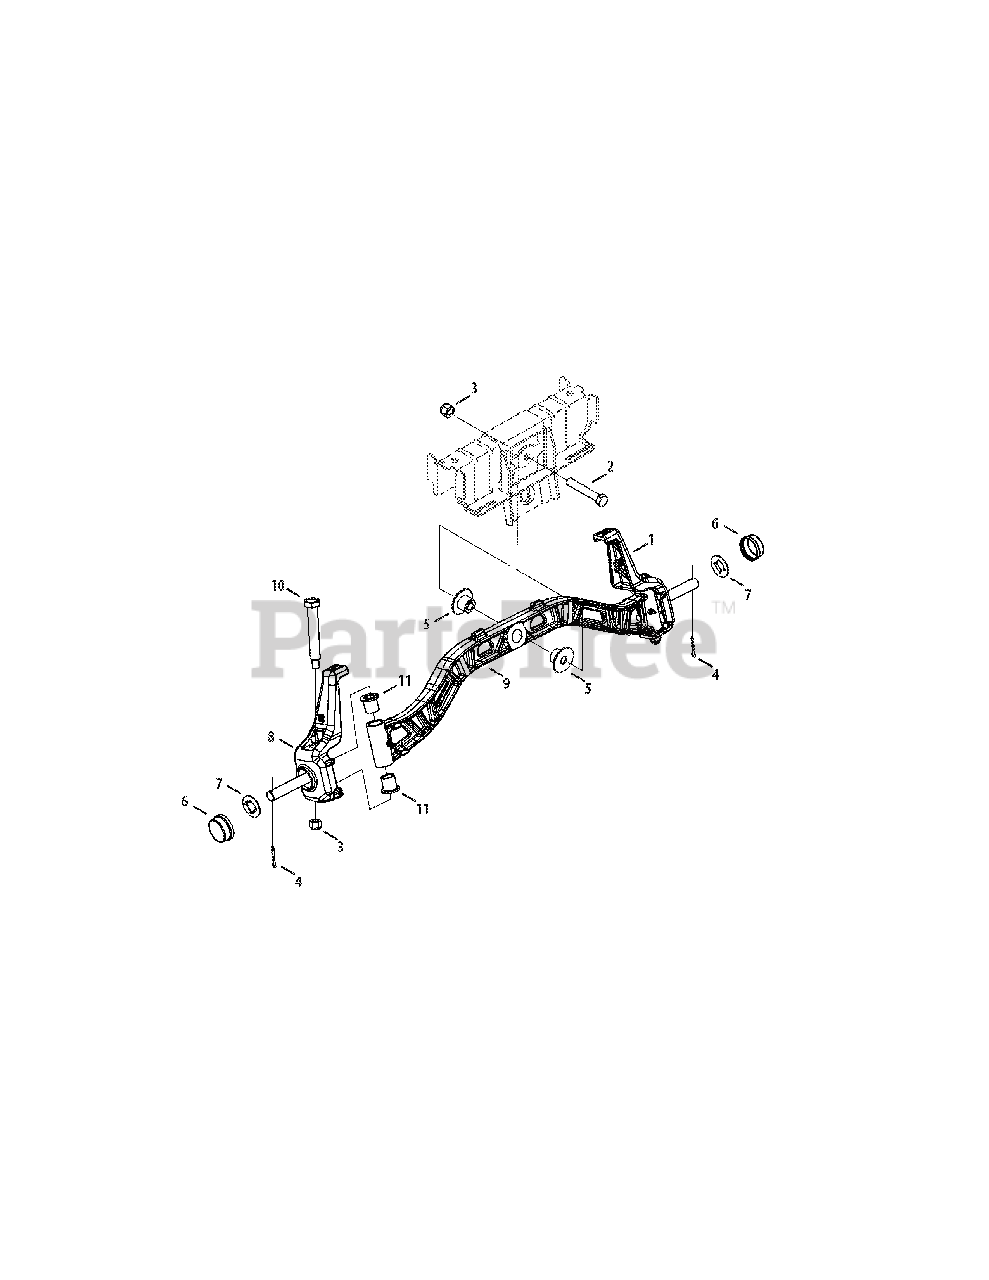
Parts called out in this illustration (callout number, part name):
1	Steering Axle Assembly, LH
2	Hex Cap Screw, 1/2-13 x 3.00
3	Nut, Hex Lock, 1/2-13
4	Pin, Cotter, 5/32, 1.25
5	Shoulder Spacer, 1.00 x .515 x .760
6	Hub Cap
7	Washer, Flat, .350 x 1.559 x .062
8	Steering Axle Assembly, RH
9	Pivot Axle, Cast
10	Shoulder Bolt, .75 x 4.20, 1/2-13
11	Flange Bearing, .75 x 1.00 x 1.12
